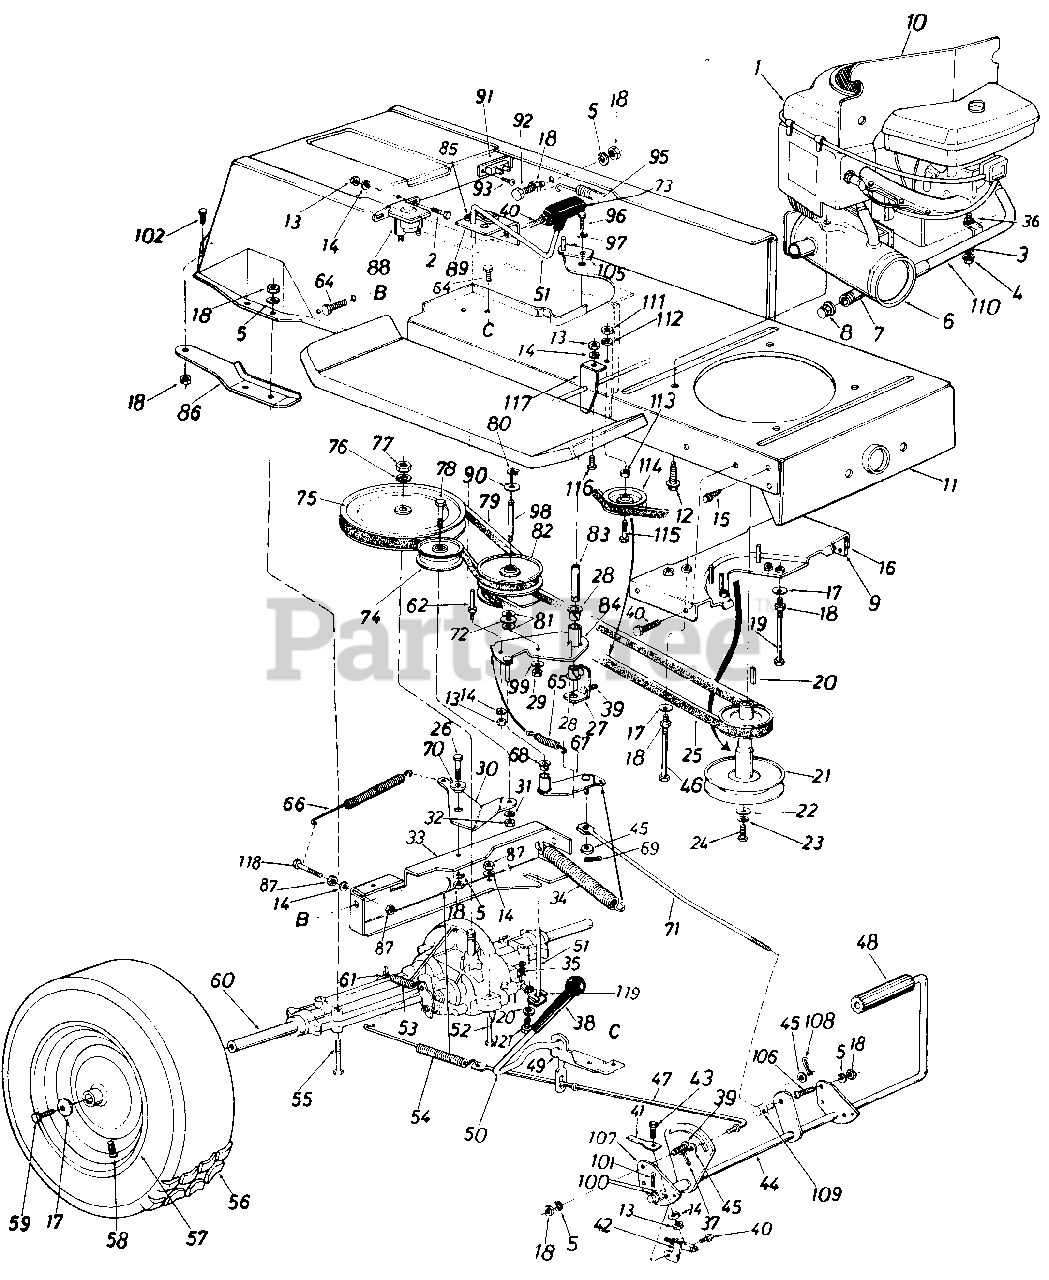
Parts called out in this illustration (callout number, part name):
1	Engine
2	Hex Bolt 1/4-20 x .62" Lg.
3	Special L-Wash. 5/16" I.D.
4	Hex Nut 5/16-18 Thd.
5	L-Wash. 5/16" I.D.
6	Exhaust Muffler
7	Pipe Nipple
8	Cap Oil Drain
9	Brake Cable Brk't.
10	Heat Shield
11	Lower Frame Ass'y.
12	Hex Wash. Hd. TT-Tap Scr. 3/8-16 x 1.25" Lg.
13	Hex Nut 1/4-20 Thd.
14	L-Wash 1/4" I.D.
15	Hex Wash. Hd. AB-Tap Scr. 5/16" x .75" Lg.
16	Belt Guard Brkt. Ass'y.
17	Bell-Wash. .345" I.D. x .88"
18	Hex Nut 5/16-18 Thd.
19	Hex Bolt 5/16-18 x 4.00"
20	Sq. Key 1/4" X 1/4 X 2.00"
21	Engine Pulley
22	Fl-Wash. 7/16" I.D. x 1.25"
23	L-Wash. 7/16" I.D.
24	Hex Bolt 7/16-20 x 1.50" Lg.
25	Variable-Speed Belt
26	Hex Bolt 5/16-18 x .75" Lg.
27	Bearing Shaft Bracket Ass'y.
28	Flanged Nyliner Brg. 518" I.D. x .88" Lg.
29	Hex Nut 3/8-24 Thd.
30	Idler Bracket
31	L-Wash. 3/8" I.D.
32	Hex Nut 3/8-24 Thd.
33	Transaxle Support Brkt.
34	Ext. Spring .94" O.D. x 6.7
35	Inter. Cotter Pin
36	Fl-Wash. .34" I.D. x .62" O.D. x .033
37	Cotter Pin 3/32" Dia. x .75"
38	Grip Black
39	Truss Mach. Scr. 5/16-18 x .75" Lg.
40	Hex Wash. Hd. Self-Tap Scr. 1/4-20 x .50" Lg.
41	Switch Actuator
42	Safety Switch
43	Hex Bolt 1/4-20 x 1.0" Lg.
44	Clutch & Brake Pedal Ass'y.
45	Fl-Wash.
46	Hex Bolt 5/16-18 x 4.5"
47	Brake Rod 20.9" Lg.
48	Foot Pad
49	Brake Lever Bracket
50	Hill Holder Brake Handle
51	Shift Lever Ass'y.
52	Hex Bolt 1/4-28 x 1.75" Lg.
53	Ext. Spring .38 O.D. x 2.5"
54	Ext. Spring .59" O.D. x 7.08"
55	Hex Bolt 5/16-18 x 2.75
58	Air Valve
59	Hex Bolt 5/16-24 x .75" Lg.
60	Transaxle Complete R.H.
61	Brake Return Spring Anchor
62	Belt Guard Pin 1/4-20 Thd.
64	Hex Wash. TT-Tap Scr. 5/16 x .62" Lg.
65	Ext. Spring .50" Dia.
66	Ext. Spring .62" O.D. x 6. 1 2"
67	Variable Speed Torque Brkt. Ass'y.
68	Flanged Bearing
69	Cotter Pin 3/32" Dia.
70	Shoulder Spacer .500" Dia. x.27" Lg.
71	Speed Control Link
72	Truss Bearing .56 Dia. x 1 .25"
73	"T" Knob
74	Fl-Idler Pulley 3.25" x 1.0"
75	1/2" "V"-Pulley 8.0" O.D. x .501 " I.D.
76	L-Wash. 1/2" I.D.
77	Hex Jam Nut 1/2-20 Thd.
78	Hex Bolt 3/8-24 x .75" Lg.
79	Variable Speed Belt
80	Snap Ring .56" Dia.
81	Fl-Wash.
82	Variable Speed Pulley Ass'y. 5" O.D.
83	Bearing Shaft
84	Variable Speed Brkt. Ass'y.
85	Comp. Spring Clip
86	Transaxle Support Brkt. R.H.
87	Hex Nut 1/4-28 Thd.
88	Solenoid
89	Shift Lever Bracket
90	Teflon Washer
91	Circuit Breaker
92	Hex Bolt 5/16-18 x 1.50"
93	Truss Hd. Phil. Scr. #10 x 1/z Lg.
95	Ext. Spring .99" O.D. x 11.0"
96	Hex Bolt 3/8-24 x .75" Lg.
97	Bell-Wash. .38" I.D. x .88"
98	Shaft .56" Dia. x 3.875" Lg.
99	Bell-Wash. .39" I.D. x 1.12"
100	Fl-Wash.
101	Cotter Pin 3/32" Dia. x .75"
102	Hex Wash. Hd. Scr. 5/16-18 x.62" Lg.
105	Belt Guard
106	Hex Bolt 5/16-18 x .75" Lg.
107	Pedal Bracket
108	Cotter Pin 3/32 x .75"
109	Ferrule
110	Inlet Tube Ass'y.
111	Hex Nut 3/8"-16 Thd.
112	L-Wash. 3/8" I.D.
113	Fl.Wash. .390" I.D. x 1.12"
114	Fl-Idler w/Flanges 2.750
115	Hex Bolt 3/8-16 x 2.00" Lg.
116	Hex Bolt 1/4-20 x .62" Lg.
117	Spring Hanger Bracket
118	Hex Bolt 1/4-28 x 1.25" Lg.
119	Shift Lever Link Ass'y.
120	Bell-Wash. .265 I.D. x .75 O.D.
121	Hex Bolt 1/4-28 x .62" Lg.
